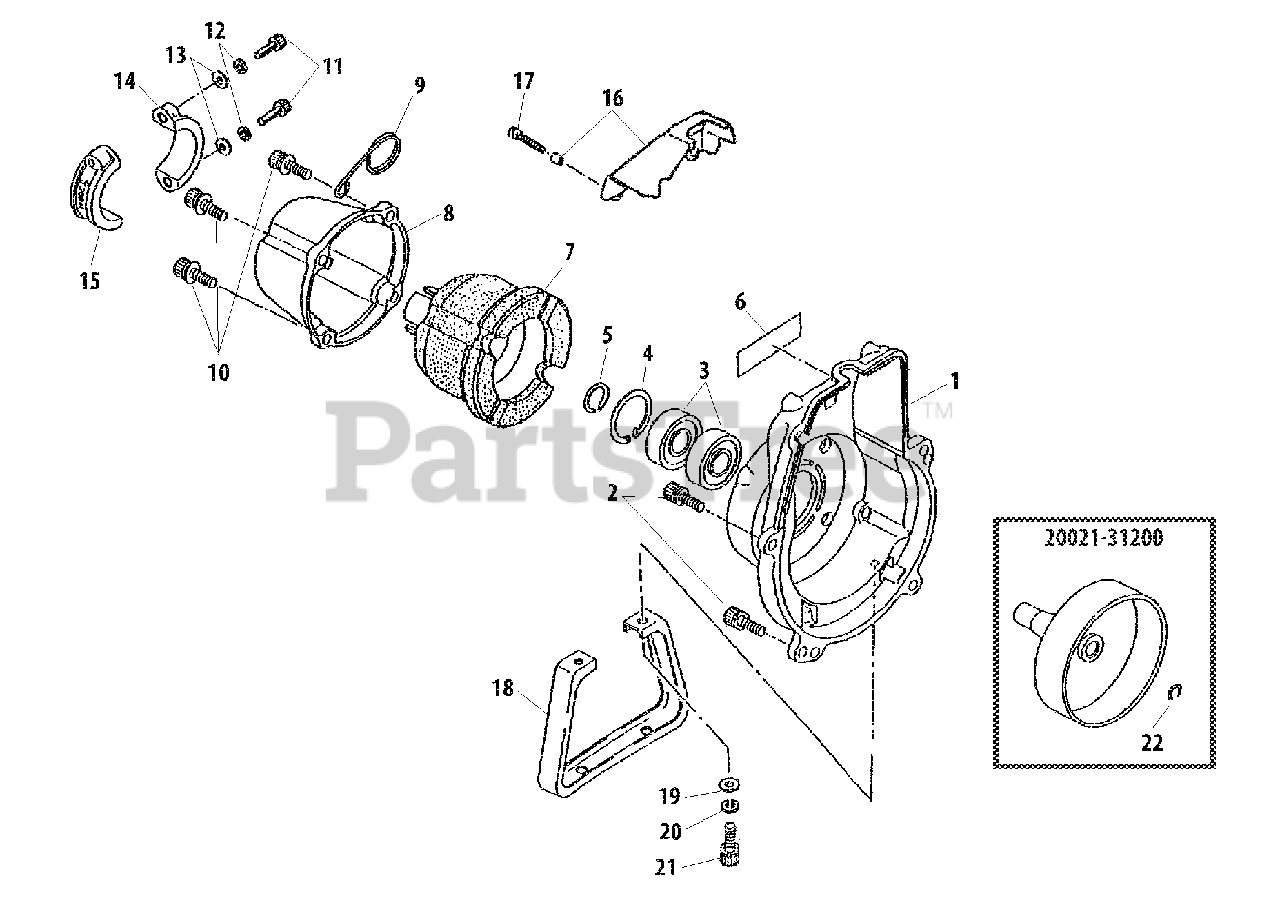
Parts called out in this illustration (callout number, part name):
1	COVER, FAN
2	BOLT M5×20
3	BEARING, BALL 6002 DDU
4	RING, SNAP Ø32
5	RING, SNAP
6	LABEL, TRADE
7	CUSHION, AV
8	CAP, CUSHION
9	HOLDER, CABLE
10	BOLT M5×20
11	BOLT 5×25
12	WASHER, SPRING 5
13	WASHER, FLAT 5.5×10×0.8
14	CLAMP - B
15	CLAMP - A
16	GUARD, TOP
17	BOLT M4×16
18	STAND
19	WASHER 5 MM
20	WASHER, SPRING 5
21	BOLT
22	RING, SNAP Ø11.4
20021-31200	DRUM ASSY, CLUTCH
